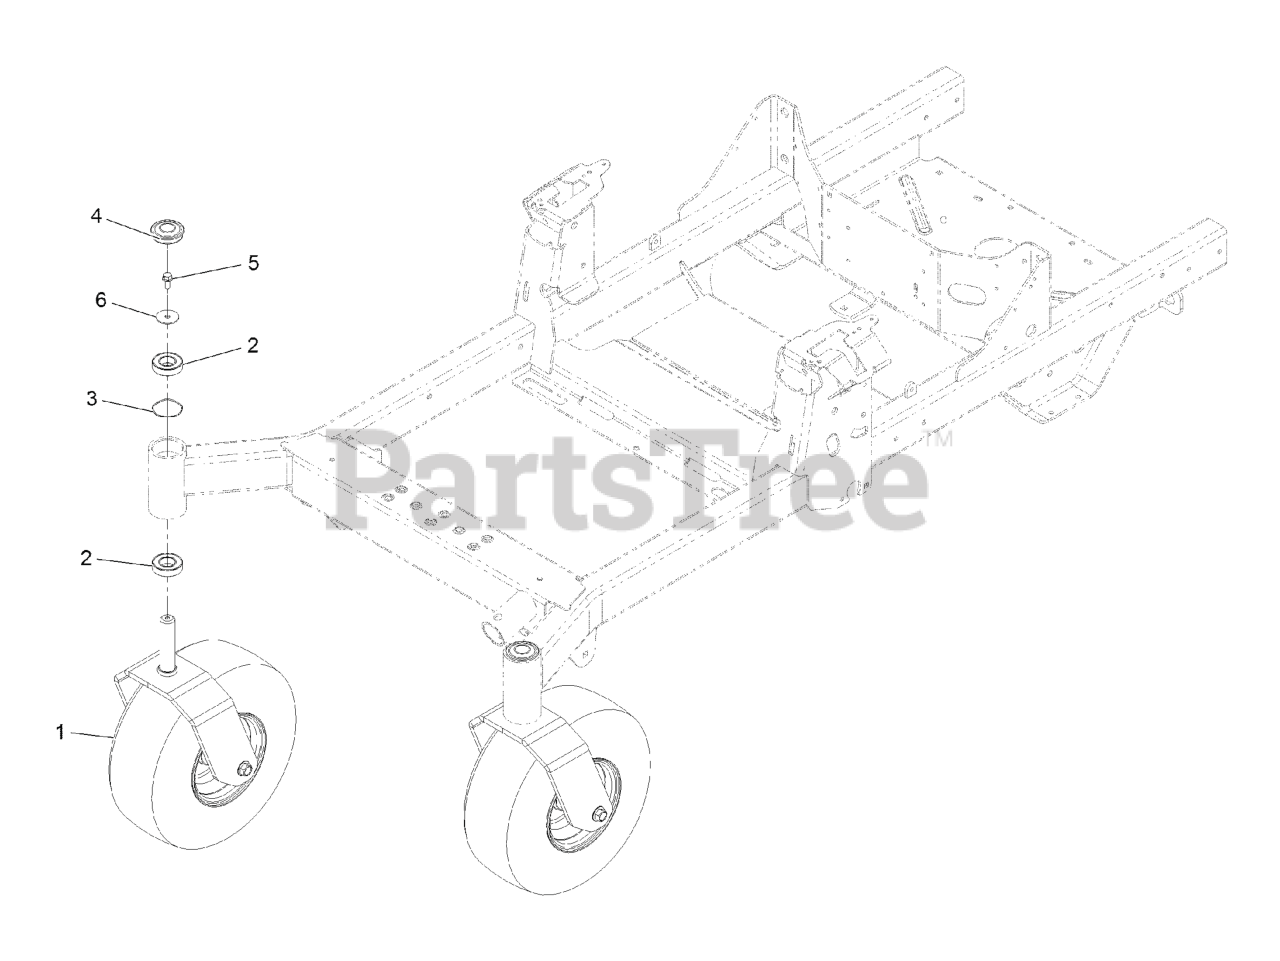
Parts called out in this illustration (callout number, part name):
1	ASM-Front Caster W/Fork
2	BEARING-BALL
4	CAP-GREASE
5	SCREW-HHF
6	WASHER-FLAT
